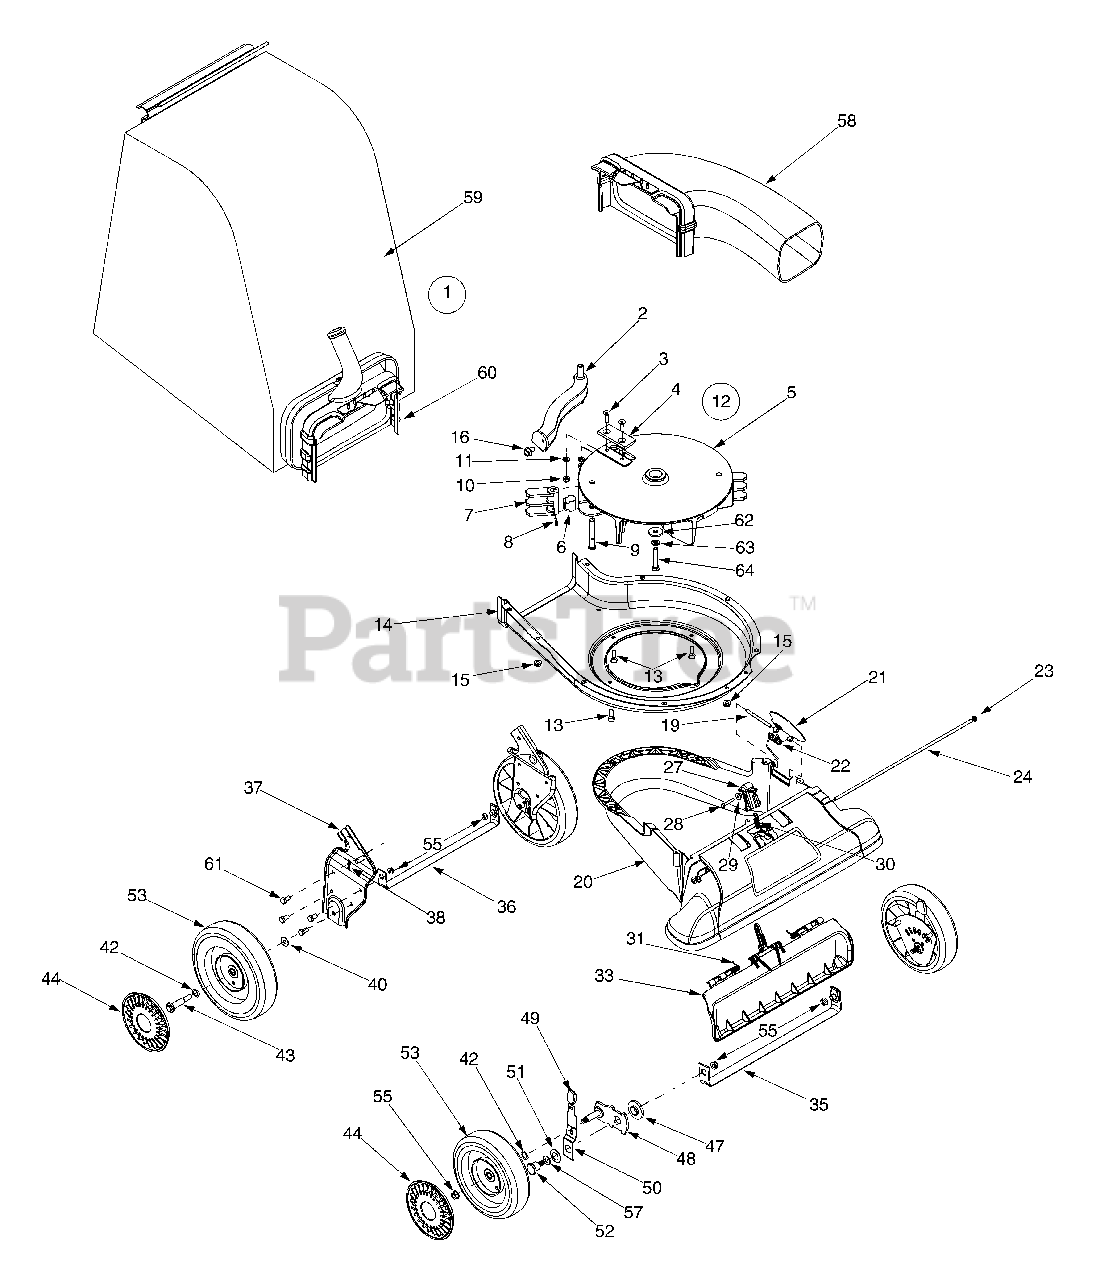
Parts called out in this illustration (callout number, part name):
1	Bag Assembly
3	Hex Screw 5/16-24 x 1.0
4	Chipper Blade
5	Impeller
6	Pin Clip
7	Flail
8	Spiral Pin
9	Clevis Pin
10	Lock Nut, 5/16-24
11	Lock Washer, 5/16
12	Impeller Assembly
13	Shoulder Screw, #12-24 x.30 x.46
15	Flange Lock Nut 5/16-18
16	Screw, 5/16-18 x.500
19	Hinge Pin
20	Nozzle
21	Base Adapter Door
22	Torsion Spring
23	Cap Speed Nut 1/4
24	Pivot Rod
27	Nozzle Door Lever
28	Hex Screw, #8-18 x 1.25
29	Shoulder Spacer
30	Extension Spring
31	Nozzle Door Torsion Spring
33	Nozzle Door
38	Cotter Pin
40	Bell Washer.401 ID x.870 OD
42	Wave Washer.531 ID x.781 OD
43	Shoulder Screw 3/8-16
44	Hubcap
47	Height Adjustment Bearing
48	Pivot Arm Assembly
49	Height Adjustment Knob
50	Spring Lever
51	Bell Washer.760 ID x.25 OD
52	Shoulder Screw,.750 x.500
53	Wheel 8 x 2.125
55	Flange Lock Nut, 3/8-16
57	Thrust Washer.375 ID x.70 OD
58	Blower Chute
59	Bag
60	Chute Assembly
61	Hex Index Screw, 5/16-12 x.750
62	Flat Washer.375 ID x 1.25 OD
63	Lock Washer 3/8
64	Hex Cap Screw 3/8-24 x 2.0
